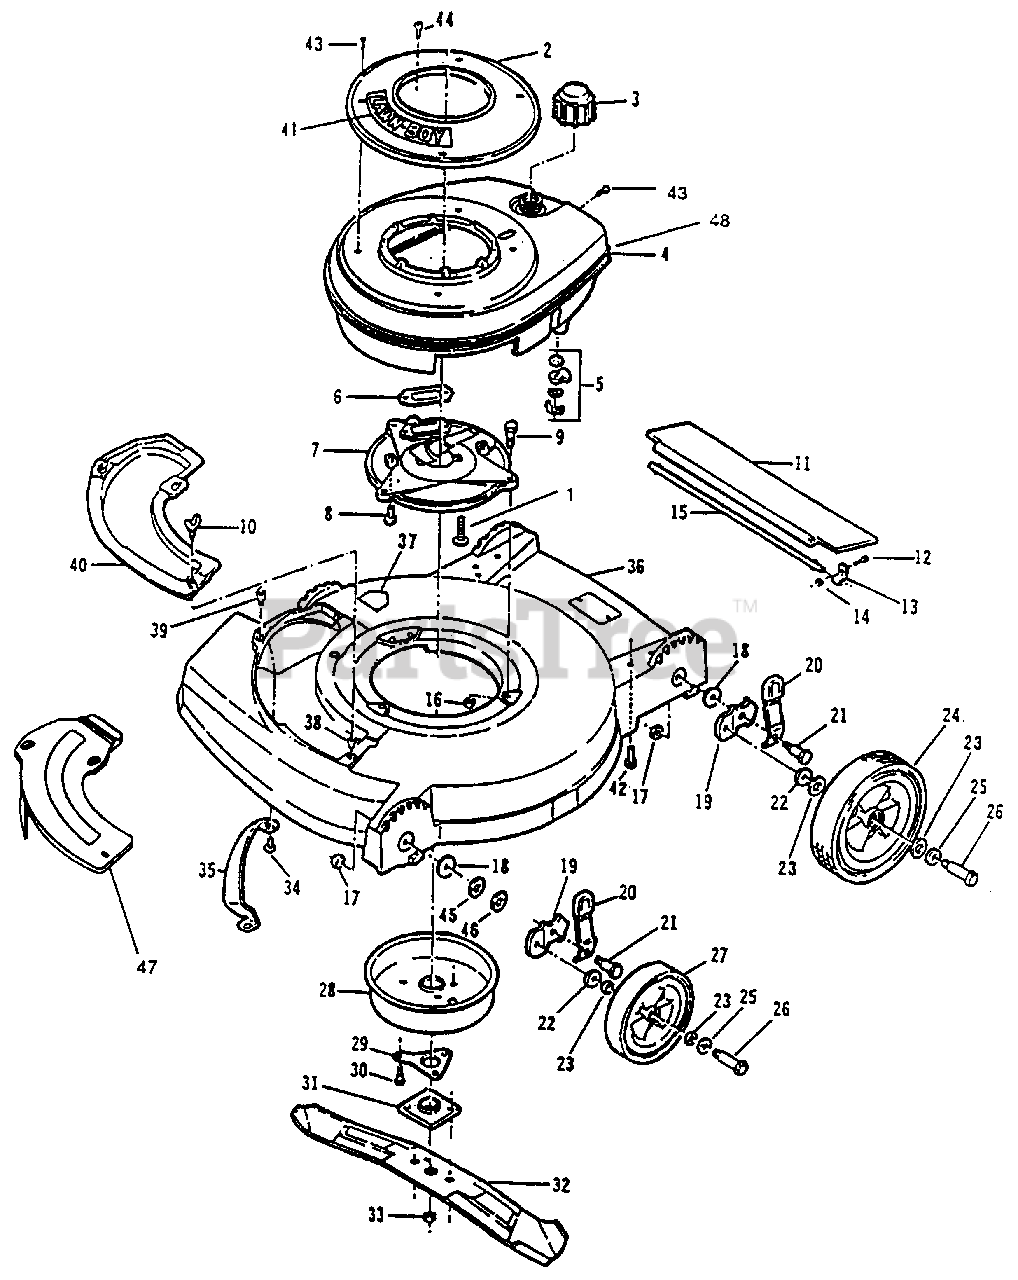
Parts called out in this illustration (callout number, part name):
1	Screw-Muffler Plate To Block
2	Starter Base & Nut Assembly
3	Fuel Cap
4	Shroud-Engine (Inc. 5)
5	Fuel Shut-Off Assembly
6	Gasket-Exhaust
7	Plate-Muffler
8	Screw-Muffler Plate to Block
9	Screw-Muffler Plate to Housing
10	Wing Screw
11	Shield-Trailing
12	Screw
13	Clamp
14	Nut
15	Rod-Trailing Shield
16	Nut-Muffler Plate to Housing
17	Nut-Wheel Height Adjust
18	Washer-Wheel Height Adjust
19	Bracket-Wheel Height Adjust
20	Knob & Spring Assembly
21	Bolt-Shoulder
22	Washer
23	Washer-Felt
24	Wheel-Rear
25	Washer-Wheel Bolt
26	Bolt-Wheel
27	Wheel-Front
28	Muffler Cover Assembly
29	Support-Crankshaft
30	Screw-Muffler to Muffler Plate
31	Collar & Plate Assembly
32	Blade-21"
33	Nut
34	Screw
35	Toe Bar
36	Housing Assembly (Inc. 37-38)
37	Decal-Blade Contact Warning
38	Grommet
39	Screw-Plate Mounting
40	Cover Plate
41	Applique-Starter Base
42	Screw-Handle Bracket to Hsg.
43	Screw-Shroud
44	Screw-Starter Mounting
45	Washer-Shim
46	Washer-Shim
47	Mulch Plate Accessory
48	Decal-Fuel Mix
